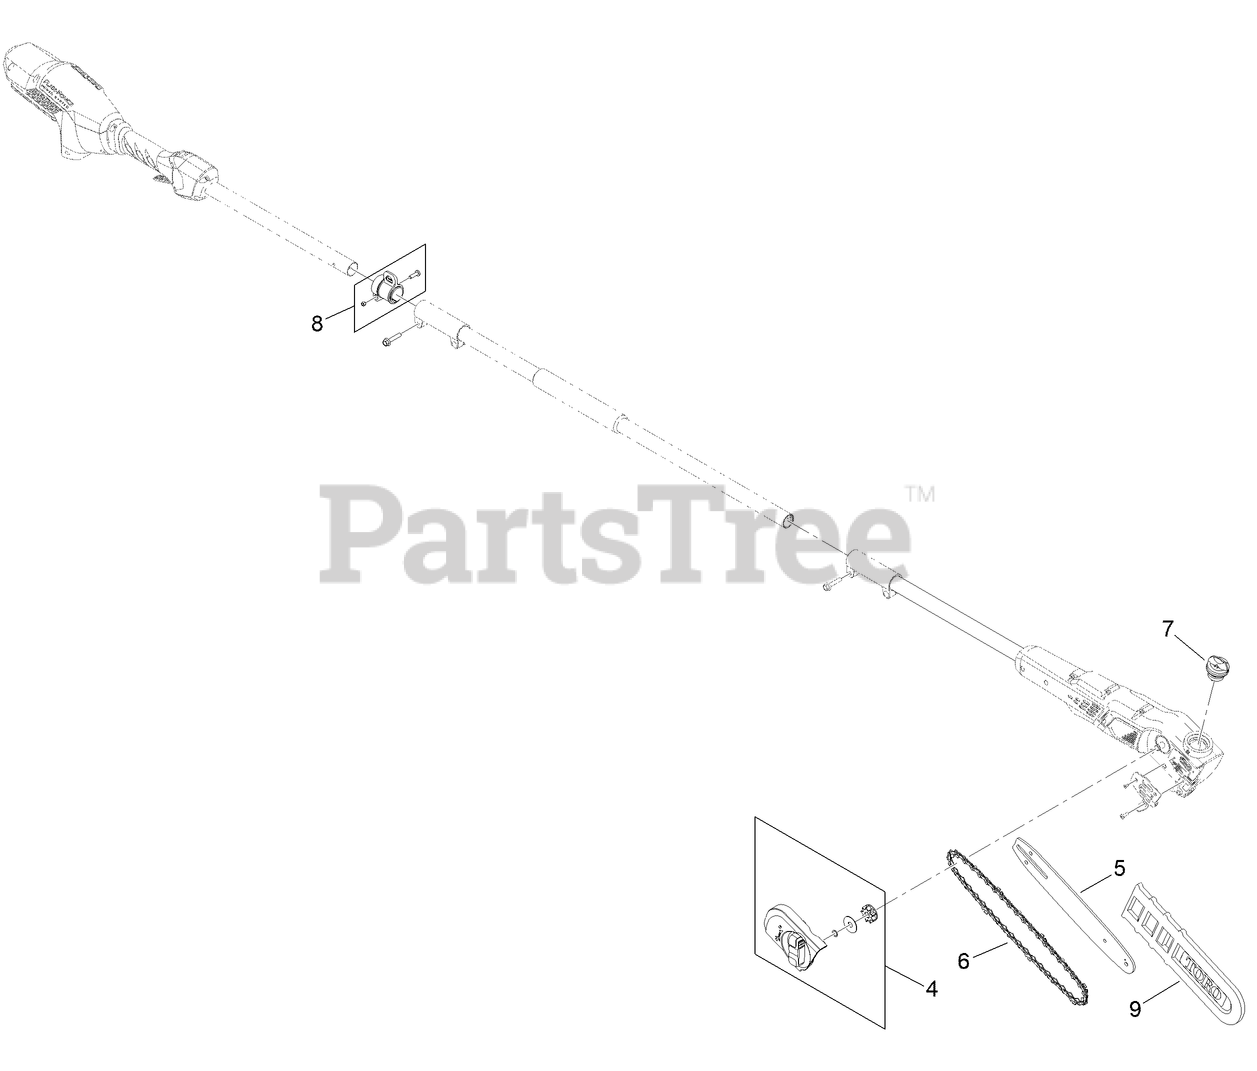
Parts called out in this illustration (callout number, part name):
4	TENSIONER ASM
6	CHAIN
7	CAP-OIL
8	COLLAR-STRAP
9	SLEEVE-BAR
